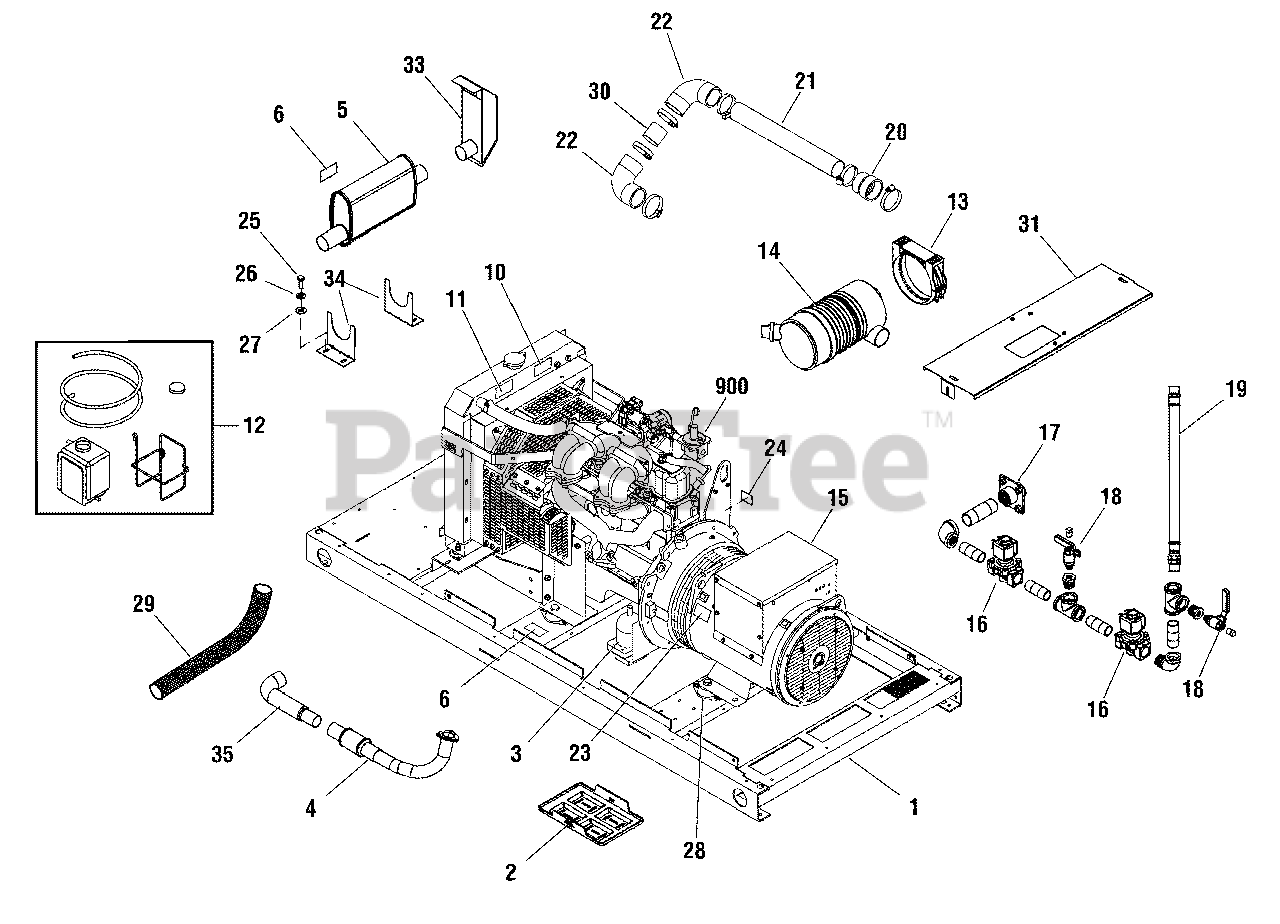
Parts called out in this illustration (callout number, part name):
1	BASE
5	MUFFLER
6	DECAL
11	DECAL
12	BOTTLE, Overflow
24	DECAL
25	* CAPSCREW, Hex Head, 1/4-20 x 3/4
26	* WASHER, Lock, 1/4-M6
27	WASHER, Fender
28	MOUNT, Vibration
33	DIFFUSER
34	BRACKET, Muffler
900	** ENGINE
